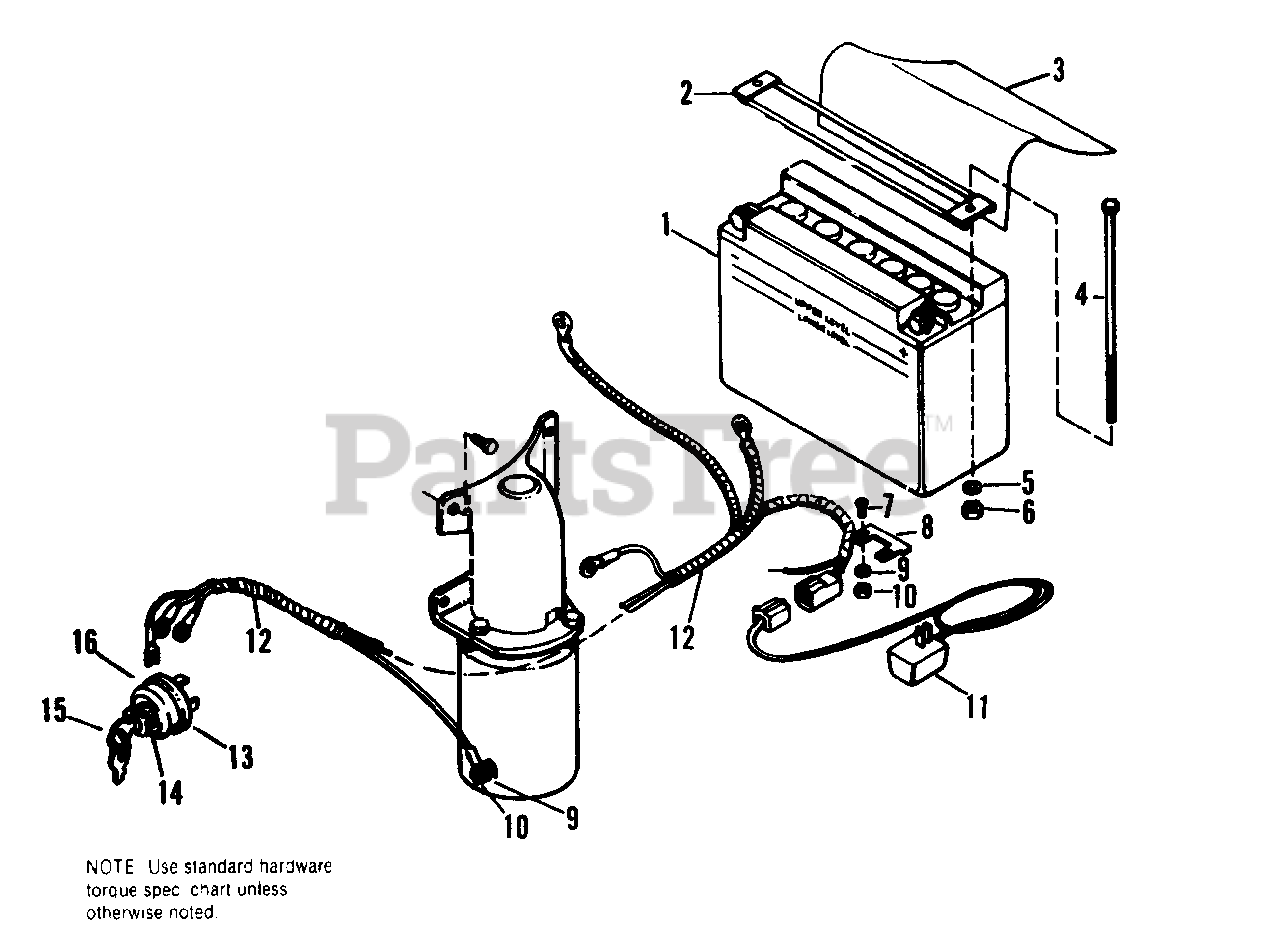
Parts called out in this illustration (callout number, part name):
2	HOLD DOWN, Battery
3	INSULATION, Battery
4	CAPSCREW, Hex Hd., 1/4-20 x 7
5	LOCKWASHER, 1/4
6	NUT, Hex, Full, 1/4-20
7	SCREW, Machine, #10-32 x 1/2
8	CLIP, Mounting
9	LOCKWASHER, Ext., #10
10	NUT, Hex, Full, #10-32
11	CHARGER ASSY.
12	HARNESS ASSY.
13	SWITCH, Key
14	NUT, Hex, Special, 5/8-32
16	LOCKWASHER, Int., 5/8
